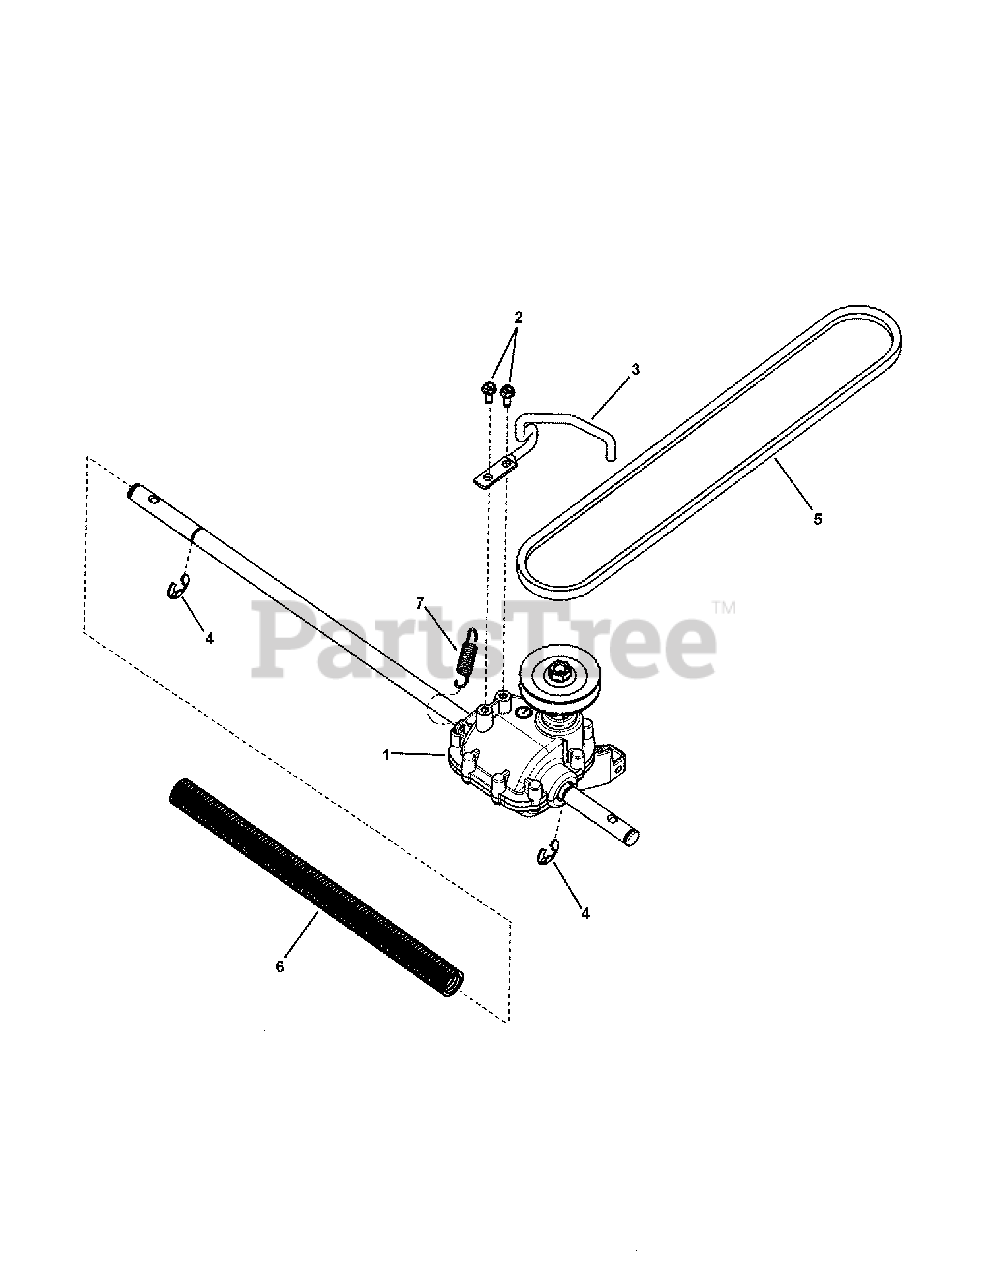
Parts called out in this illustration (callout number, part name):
1	TRANSMISSION, Varaible Speed, Front Wheel Drive
2	SCREW, #10-14 x 1/2" Hex Washer Self-Tap, Plastite
3	GUIDE, Belt, FWD
4	RETAINING RING, .392 Ext.
5	BELT, 3L, Traction Drive, 22" WBM, FWD
6	SHIELD, Axle
7	SPRING, Tension, FWD React Drive
